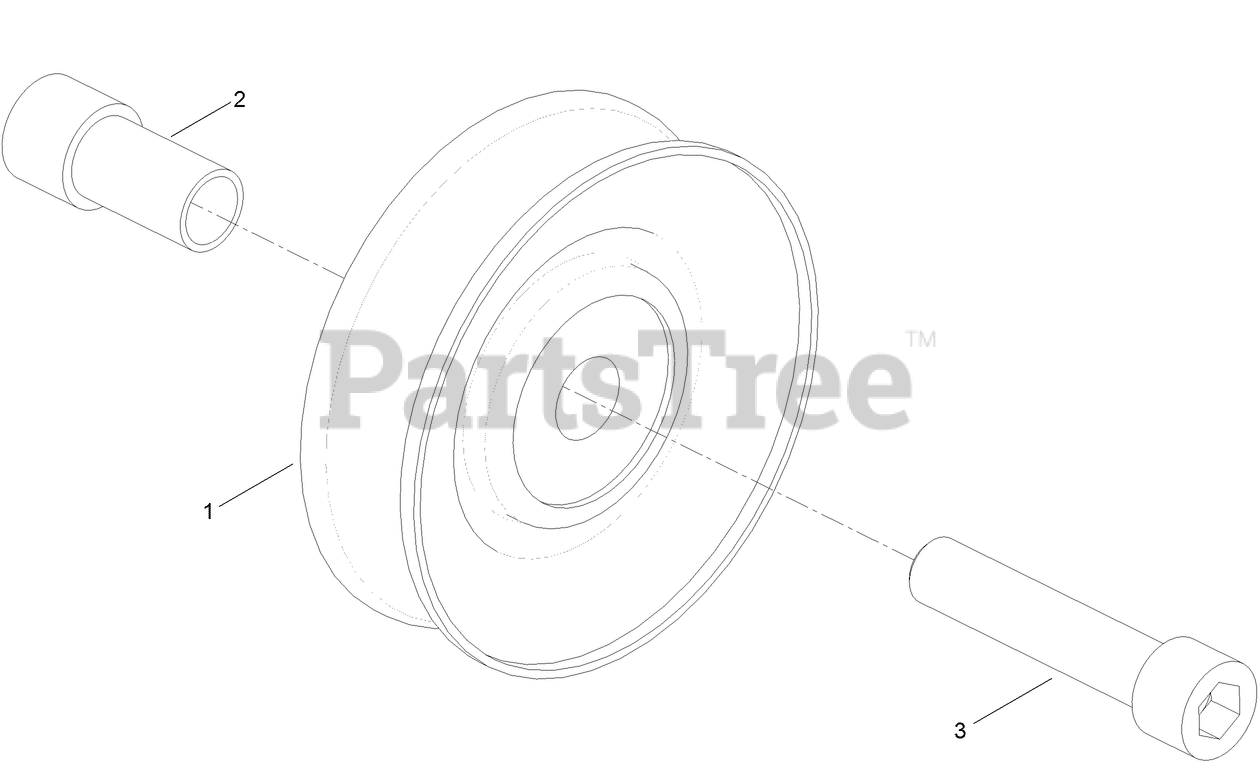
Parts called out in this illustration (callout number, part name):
1	IDLER-V, TROWEL
2	SPACER-IDLER, TROWEL
3	SCREW-HSH
